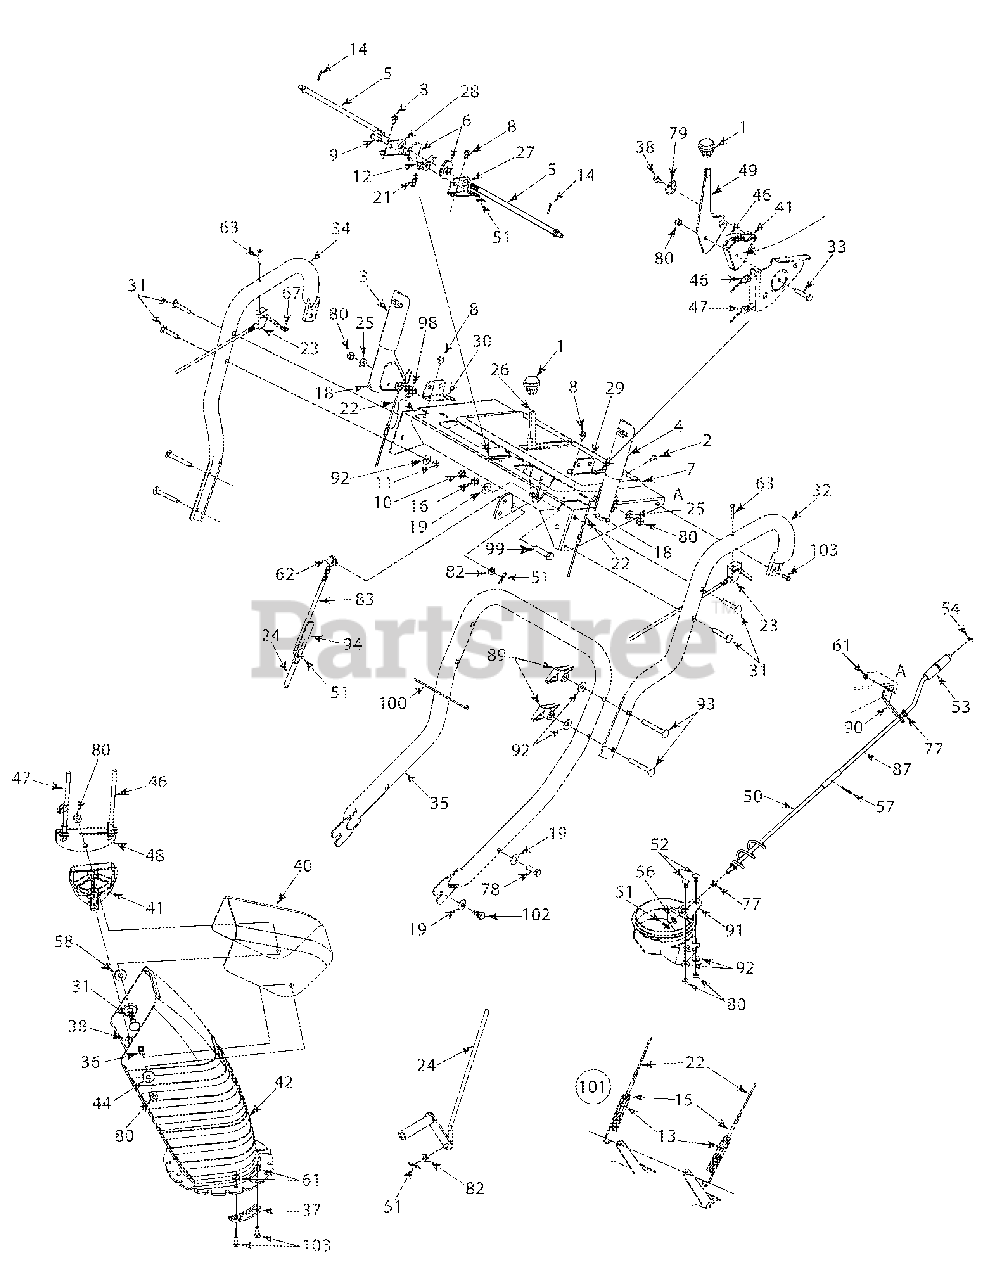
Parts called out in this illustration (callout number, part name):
1	Shift Knob
2	Truss Mach B-Tapp Scr #10-16 x .50 Gr. 5
3	Engagement Handle RH Black
4	Engagement Handle LH Black
5	Cam Rod
6	Cam Handle Lock
9	Clevis Pin .31 Dia. x 1.0" Lg.
10	Hex Nut 3/8-24 Gr. 5
11	Hex Nut 5/16-18 hd. Gr. 5
12	Cam Lock Pawl
13	Hex Ins. Locknut 1/4-20
14	Cotter Pin 3/32 x .75
15	Extension Spring
16	Compression Spring .39 ID x .88 Lg
18	Rubber Bumper
19	Cupped Washer .401 ID x .870 OD x .063
21	Compression Spring .36 DIA x 1.0" LG.
22	Clutch Cable
23	Trigger Assembly
24	Lower Shift Rod
25	Washer (special)
31	Carriage Bolt 5/16-18 x 1.75" Lg.
33	Hex Cap Scr. 5/16 - 18 x 1.50" Lg. Gr. 5
36	Carriage Bolt 5/16-18 x 1.00" Lg
37	Chute Flange Keeper
38	Hex HL In dex Washer Screw 1/4-15 X .75
40	Upper Chute Remote Tilt
41	Cable Guide
42	Lower Chute Remote Tilt
44	Flat Washer .349 ID x .879 OD x .063
46	Chute Control Cable 66"
47	Chute Control Cable w/clip
52	Carriage Bolt 5/16-18 x .75 Gr. 2
53	Knob 1.0 x 3.2
54	Push Nut 3/8" Rod
56	Flat Washer .375 ID x .738 OD X.063
57	Internal Cotter Pin
58	Flat Washer .344 ID x 1.125 OD x .125
61	Hex Flg. L-Nut 1/4-20 Gr. F Nylon
62	Adjustment Ferrule
63	Oval C-Sunk Screw #10-24 x 1.75
77	Plastic Bushing .380 ID
78	Hex Screw 3/8-16 x 1.75 Gr.5 w/patch
79	Contour Washer
80	Hex Flg. L-Nut 5/16-18 Gr. F Nylon
81	Hex L-Flanged Nut 1/4-20 Gr. "F"
82	Flat Washer .344 ID x .688 OD x .065
83	Upper Shift Rod
84	Hex Screw 1/4-20 x .75" Lg. Gr. 5
89	Wingnut Knob, 5/16-18
92	Cupped Washer .340 ID x .872 OD x .06
93	Carriage Bolt 5/16-18 x 2.50
94	Connector - Shift Rod
98	Torsion Spring .44 ID
99	Hex Scr 3/8-24 x 1.50 Gr. 5
100	Cable Tie
101	Auger/Drive Cable Assembly
102	Hex Screw 3/8-16 x .880 Gr. 5
103	Hex Screw 1/4-20 x 1.00 Gr. 5
